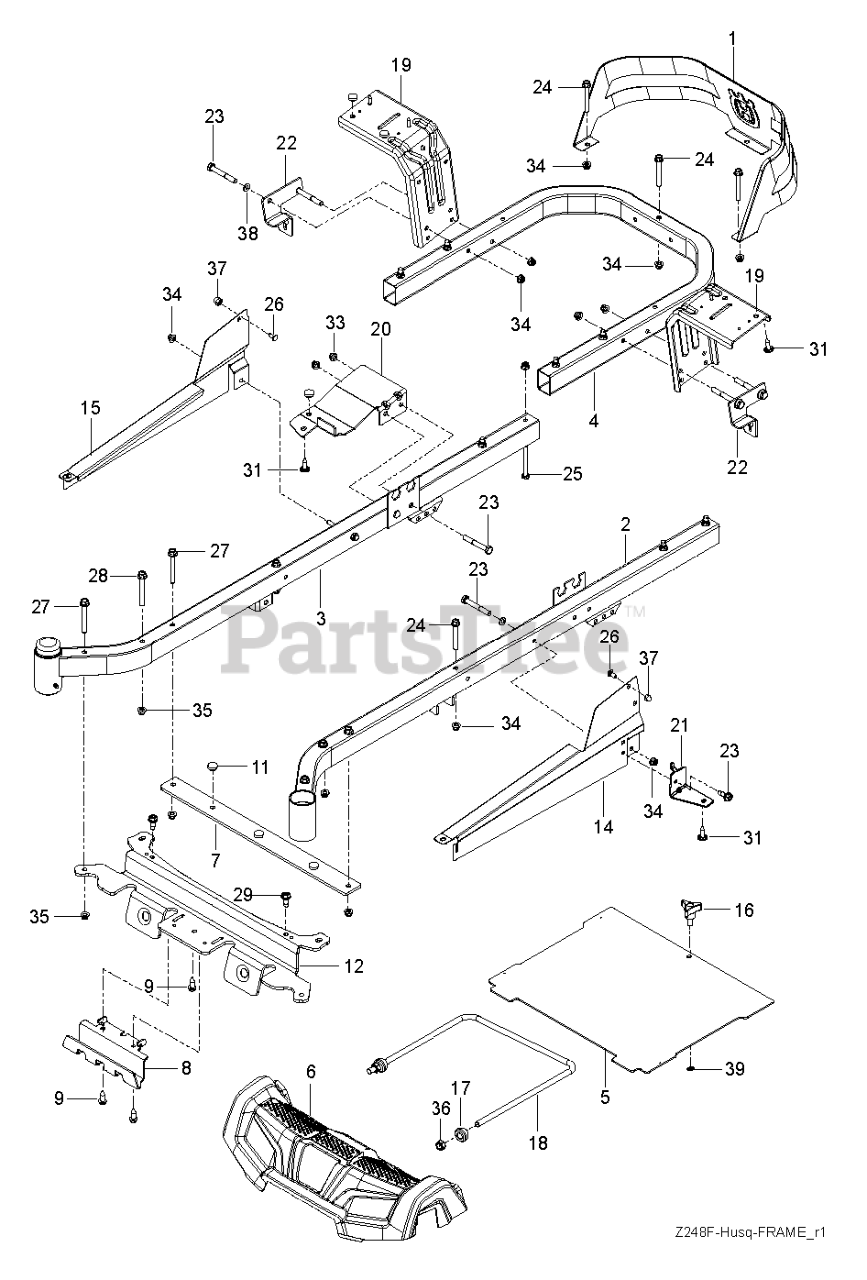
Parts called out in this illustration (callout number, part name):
1	GUARD.ENGINE.HUSQ.RZ.X498
2	FRAME.TUBE.RZ.MAIN.WELD.LH.ORG
3	FRAME.TUBE.RZ.MAIN.WELD.RH.ORG
4	TUBE.PNT.FRAME.RER.HUSQ.23".RZ
5	PLATE, FOOT W/DECALS RZ
6	COVER.FOOTREST.REFRESH.ASM
7	FOOTREST.PLATE.SUPPORT.X431
8	SKID.PLATE.PNT.RZ.REF.SIVER
9	BOLT.5/16HEX.WHS.HD
11	GROMMET.BUMPER
12	CROSS.PNT.MEMBER.BLK
14	COVER.RAIL.RH.RZ.X668
15	COVER.RAIL.LH.RZ.X668
16	KNOB W/STUD
17	BUSHING SPHERICAL SUSP. FRONT
18	LINK, FRONT SUSP.
19	FENDER.SUPPORT.PNT.X431
20	SUPPORT.PNT.RH.CONSOLE.FRONT
21	SUPPORT.PNT.LH.CONSOLE.FRONT
22	BRKT ROD.BYPASS.EZT.X431
23	BOLT.FIN HEX 5/16-18UNC X2 1/4
25	BOLT.HEX.FIN.3/8-16 X 3.GR5
26	BOLT.CARRIAGE.5/16-18.7/16
27	HHFS 3/8-16 X 3 GRD 5 ZD
28	BOLT SHOULDER,FLANGED,3/8-16X3
29	BOLT.5/16-18.THRD.ROLL.SHOULDR
31	SCREW.#10 X 0.750.BOS
33	NUT LOCK HEX FLANGE 5/16-18
34	5/16-18 NYLOC FLANGE NUT
35	NUT 3/8-16 HEX FLG NYLOC ZD
36	7/16-14 HEX NUT W/NYL RING ZD
37	NUT ACORN,FLANGED,5/16-18
38	WASHER
39	WASHER 5/16"
